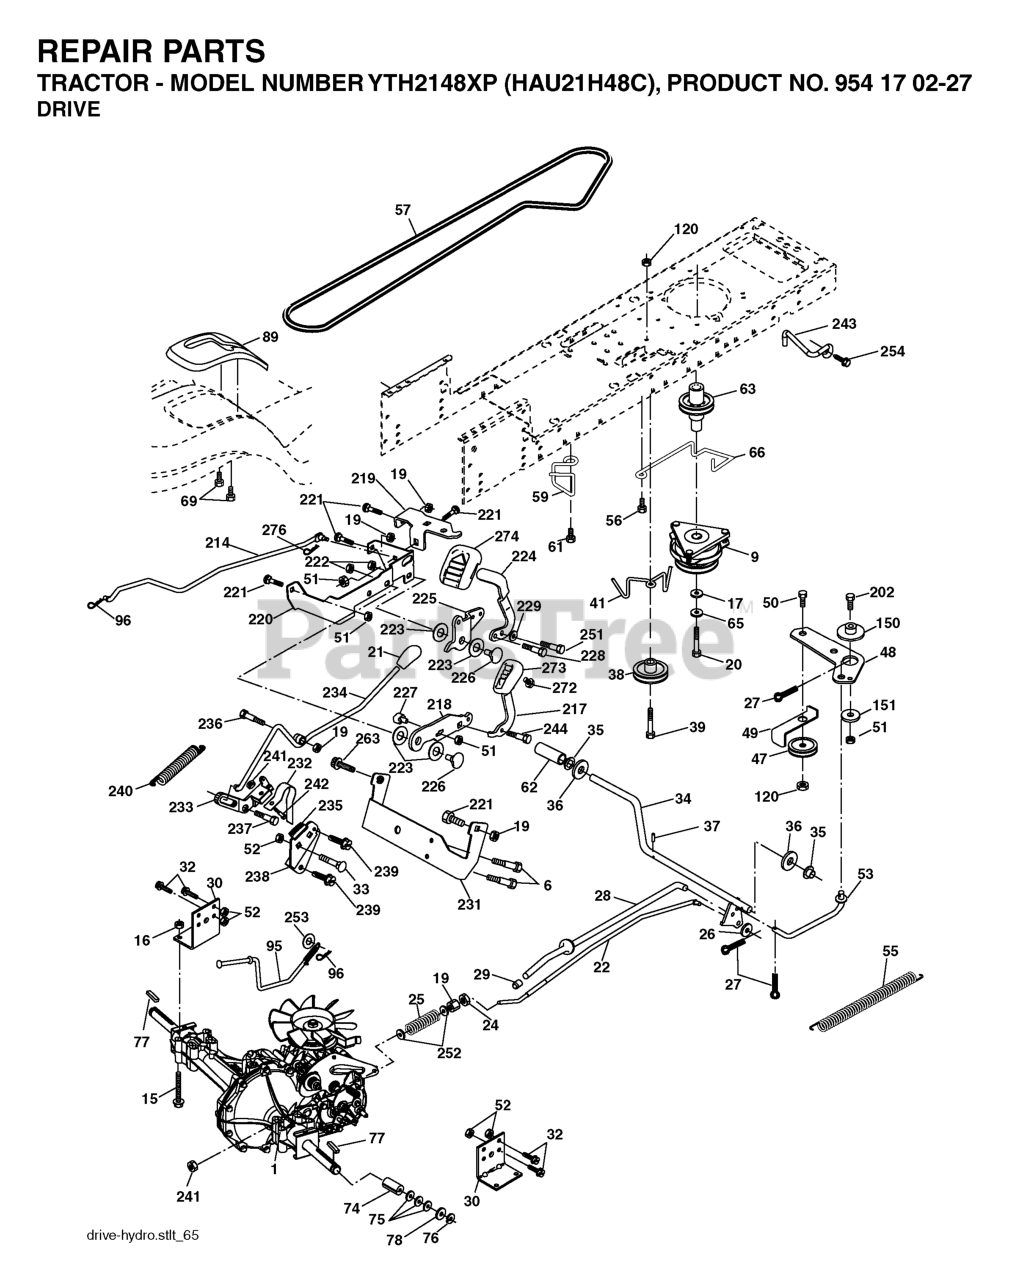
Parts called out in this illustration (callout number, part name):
6	SCREW 5/16"
9	CLUTCH ELECTRIC
15	BOLT HEX 5/16-18 GR 5
16	NUT.71038.31-18.HEX.NYLOCK
19	NUT
20	BOLT HEX 7/16-20X4-1/4"
22	ROD.BRAKE.HG-0510.PEDAL.CONTRL
24	NUT
25	SPRING BRAKE ROD
26	WASHER
27	COTTER PIN
28	ROD, PARKING BRAKE
29	PLUNGER CAP
30	BRKT, TRNSXLE MNT 20"
32	BOLT
33	RP BOLT 5/16-18 X3/4 ZN/YEL GR
34	SHAFT, FOOT PEDAL
35	BEARING.NYLON
37	DRIVE PIN
38	PULLEY IDLER COMPOSITE
41	KEEPER, BELT IDLER
47	IDLER PULLEY
48	BELLCRANK, CLUTCH
49	RETAIN BELT
50	BOLT.3/8-16X1.50
52	LOCKNUT
53	LINK, CLUTCH LT
55	SPRING, RETURN LT
56	SCREW.3/8-16
57	DRIVE BELT, LTH & YTH TRACTORS
59	KEEPER, BELT CENTER
61	SCREW 3/8-16X.875
62	PEDAL COVER T
63	PULLEY- ENGINE
65	LOCKWASHER
66	KEEPER BELT ENGINE
69	SCREW.HI-LO.CONSOLE
74	SPACER AXLE
77	SQUARE KEY
95	ROD BYPASS
96	RETAINER M
120	NUT LOCK FLG 3/8-16 UNC
150	SPACER, RETAINER
151	WASHER 12/32X2X10GA
214	LINK TRANSAXLE
217	PEDAL REVERSE
218	ARM CONTROL PEDAL REVERSE
219	BRACKET FREST PDL
220	BRACKET MTG.PDL CONTROL
221	Bolt - Rd. Hd. Sq. Neckiage 3/8 16 x 3/4
222	Nut, Crownlock Hex 7/16-14 unc
223	WASHER NYLON
224	PEDAL FORWARD
225	ARM CONTROL PEDAL FORWARD
226	BOLT PIVOT SPACER
227	CAM REVERSE PEDAL LT
228	BOLT SHOULDER
229	WASHER.SERRATED.5/16X.75
231	STRAP TORQUE
232	ACUATOR CRUISE DISENGAGE
233	PAWL CONTROL CRUISE
234	LEVER CONTROL CRUISE
235	SECTOR CONTROL CRUISE
237	SHOULDER BOLT 5/16-18TT
238	ARM MTG.CRUISE SECTOR
239	Screw 5/16-18 x 1/2 Hex, Self Tapping 5/16-18 x 1/2
240	SPRING RETURN CRUISE CONTROL
241	NUT CENTERLOCK
242	BOLT
243	BRACKET, ANTI-ROTATION
244	CAPSCREW.HXHD.FLG.5/16-18X.625
251	SCREW 5/16-18X1
252	WASHER
254	SCREW 3/8-16X1
271	SCREW, 3/8-16X3/4
272	SCREW, 5/16-18 X 1/2
274	COVER PEDAL FORWARD
